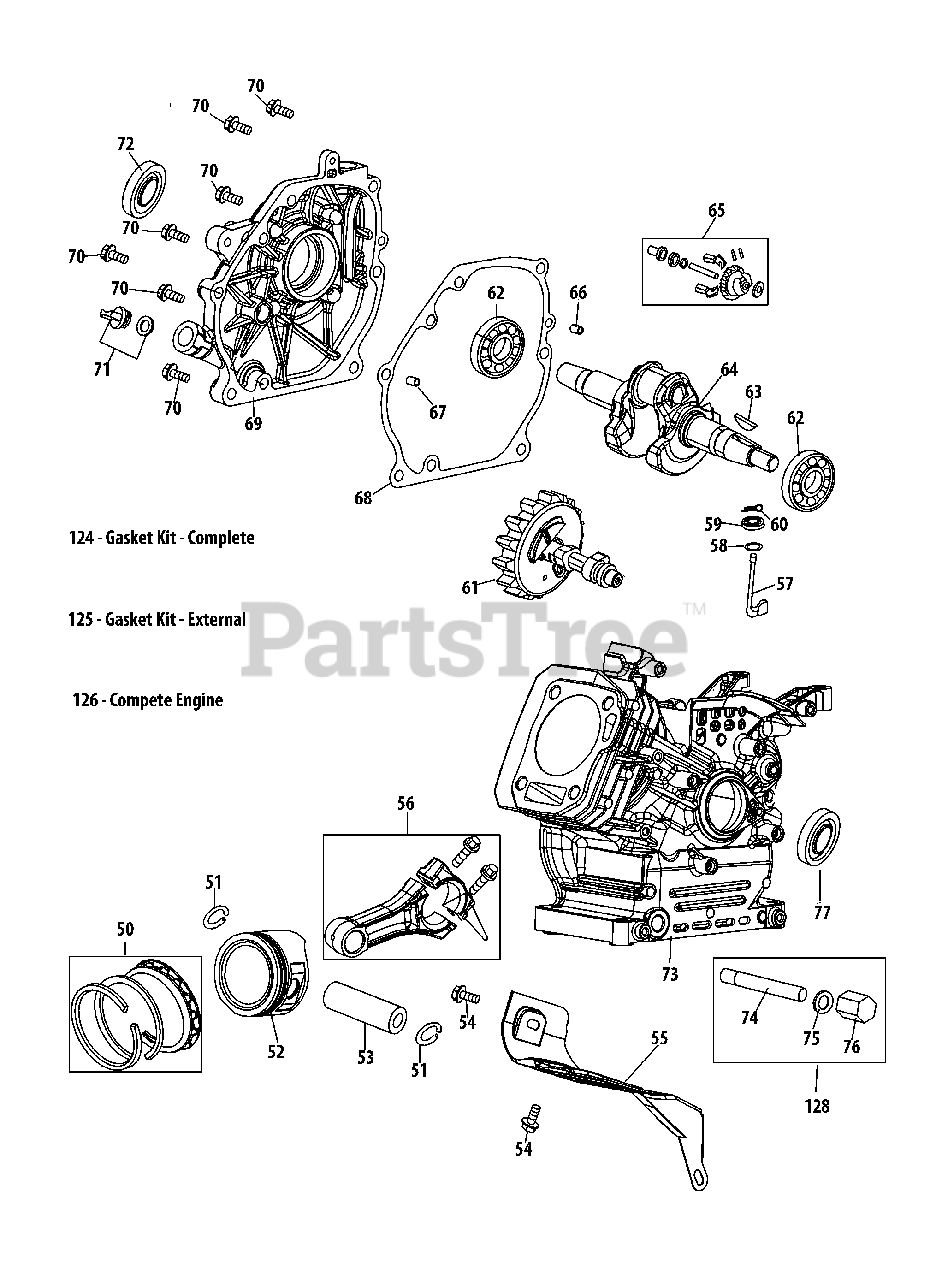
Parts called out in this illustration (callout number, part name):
50	Piston Ring Set
51	Piston Pin Snap Ring
52	Piston
53	Piston Pin
54	Bolt M6×12
55	Air Shield
56	Connecting Rod Assembly
57	Governor Arm Shaft
58	Washer 5.2×1.9
59	Governor Seal
60	Cotter Pin
61	Camshaft Assembly
62	Radial Ball Bearing, 6205
63	Key, Flywheel
64	Crankshaft Kit
65	Governor Gear/Shaft Assembly
66	Dowel Pin 7×14
67	Dowel Pin 9×14
68	Crankcase Cover Gasket
69	Crankcase Cover
69	Crankcase Cover Kit
70	Bolt M8×32
71	Oil Fill Plug Assembly
71	O-Ring Only
72	Oil Seal, 25×41.25×6
73	Short Block Assembly
73	Crankcase Kit
74	Oil Drain Pipe
75	Washer 10×16×1.5
76	Oil Drain Plug
77	Oil Seal 25×41.25×6
124	Gasket Kit - Complete
125	Gasket Kit - External
126	Complete Engine
128	Oil Drain Assembly
